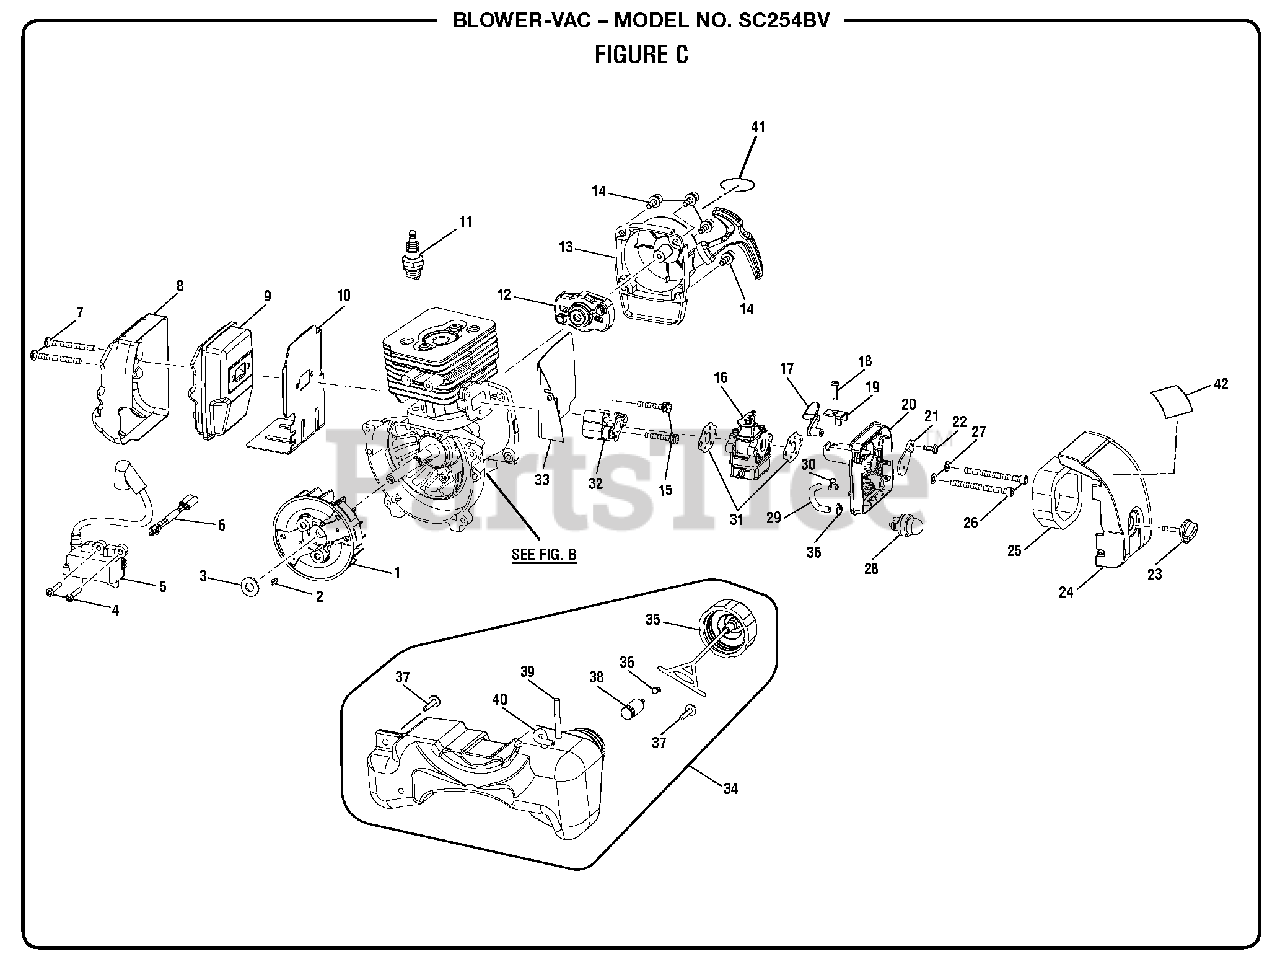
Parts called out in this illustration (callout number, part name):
2	Woodruff Key
3	Washer (ID.98 x OD30 x 3t)
4	Screw w/Washers (M4 x 22 mm, T25 Torx Soc. Hd)
5	Ignition Coil Assembly
6	Ignition Lead Assembly
7	Cap Screw (M5 x 50 mm, T25 Torx Soc. Hd.)
8	Heat Shield
9	Muffler Assembly
10	Muffler Gasket
11	Spark Plug (Champion RCJ6Y)
12	Pulley Assembly
13	Recoil Starter Assembly
14	Cap Screw w/Washers (M5 x 16 mm, T25 Torx Soc. Hd.)
15	Screw w/Washers (M5 x 31 mm, T20 Torx Pan Hd.)
16	Carburetor Assembly
17	Choke Lever
18	Screw (M4 x 16 mm, T20 Torx Pan Hd.)
19	Retaining Clip
20	Air Box Base
21	Choke Plate
22	Screw (M4 x 12 mm, T20 Torx Pan Hd.)
23	Knob
24	Air Box Cover
25	Air Filter
26	Cap Screw (M5 x 60 mm, T25 Torx Soc. Hd.)
27	Washer (ID5 x OD12 x 0.80t)
28	Primer Bulb Assembly
29	Hose (51 mm)
30	Hose Clip
31	Carburetor Gasket
33	Heat Dam Gasket
34	Fuel Tank and Cap Assembly
35	Fuel Cap Assembly
36	Hose Clip
37	Screw (10-14 x 7/8 in., T25 Torx Pan Hd.)
38	Fuel Filter
39	Rubber Tubing (225 mm, Low Permeation)
40	Rubber Tubing (114 mm)
41	Starting Instructions Label
42	Starter Cover Label
